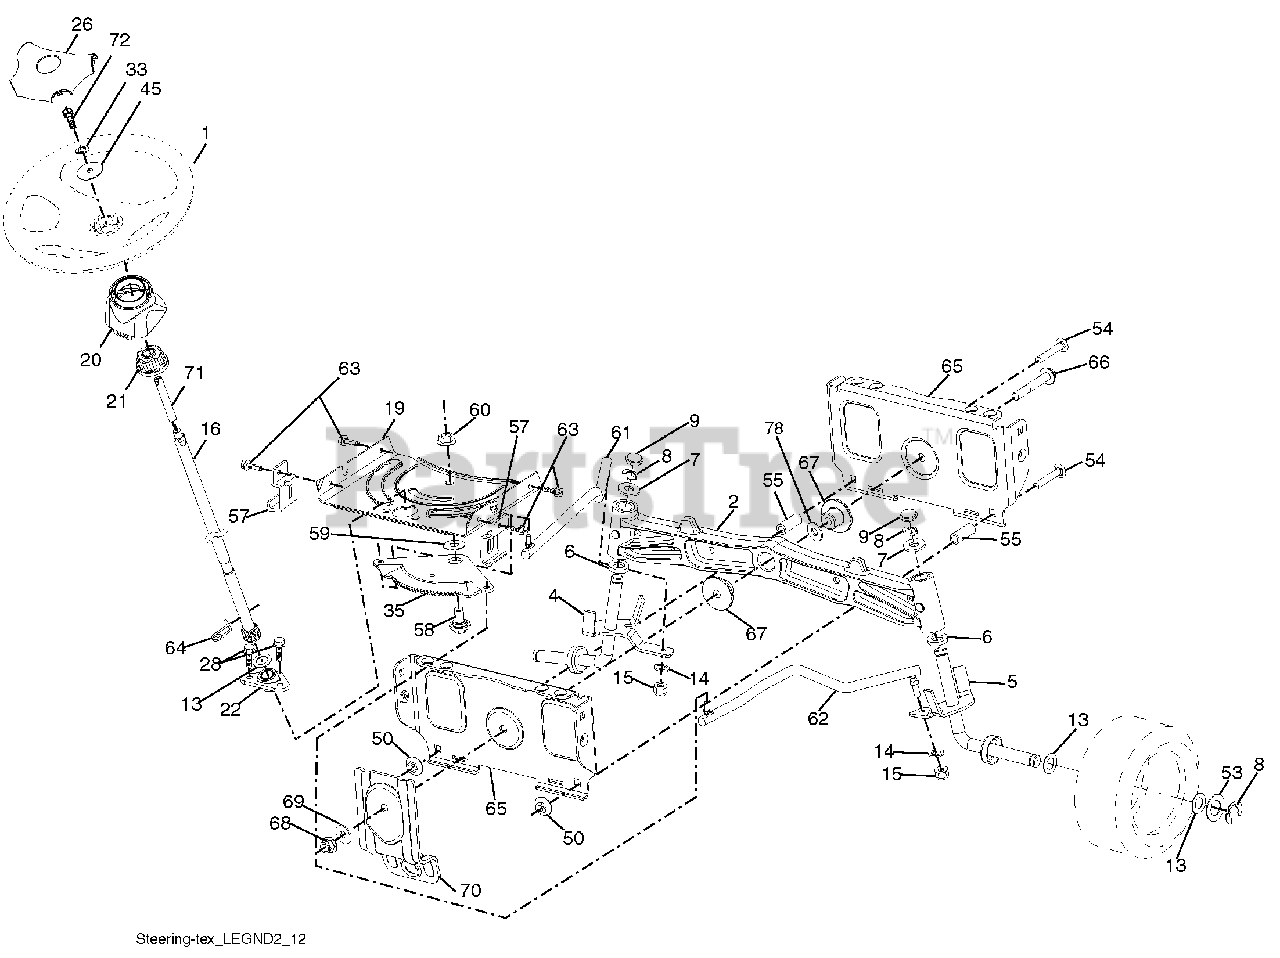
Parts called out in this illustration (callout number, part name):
1	Wheel, Steering
2	Axle Asm., Front
4	Spindle Asm., LH
5	Spindle Asm., RH
6	Bearing, Race Thrust Harden
7	Washer 25/32 x 1-5/8 x 16 Ga.
8	Ring, Clip #T5304-75
9	Cap, Spindle
13	Washer 25/32 x 1-1/4 x 16 Ga.
14	Washer Lock 3/8
15	Nut, Crown Lock 3/8-24 unf
16	Shaft Steering
19	Plate Steering
20	Boot, Steering
21	Adapter, Wheel Steering
22	Bushing, Strg. Blk
26	Insert, Wheel Steering
28	Screw 3/8-16 x 3/4
33	Washer Lock 5/16
35	Gear, Sector Plate
45	Washer 11/32 x 2-3/8 x 12 Ga.
50	Nut Lock Flg 3/8-16 unc
53	Washer Hardened .793 x 1.637 x .060
54	Bolt Hex HS 3/8-16 unc x 2-1/4
55	Spacer Brace Axle
57	Bracket Upstop
58	Bolt Shoulder Sector Pivot CFM
59	Washer Thrust Sector Steering
60	Nut Flange Lock 5/8-11
61	Draglink, LH
62	Draglink, RH
63	Screw 5/16-18 x 3/4
64	Retainer Clip Spring Steering
65	Brace Axle Front
66	Bolt Hex Fghd 7/16-14 x 3 Serr
67	Bushing PM Front Axle
68	Nut Lock Flange 7/16-14 Gr. 5
69	Washer 1.5 x .505 x .118
70	Bracket Deck Susp. Front
71	Shaft Ext. Steering
72	Bolt 5/16-18 x 4.5 Gr. 5
78	Washer Thrust .515 x .750 x .033
